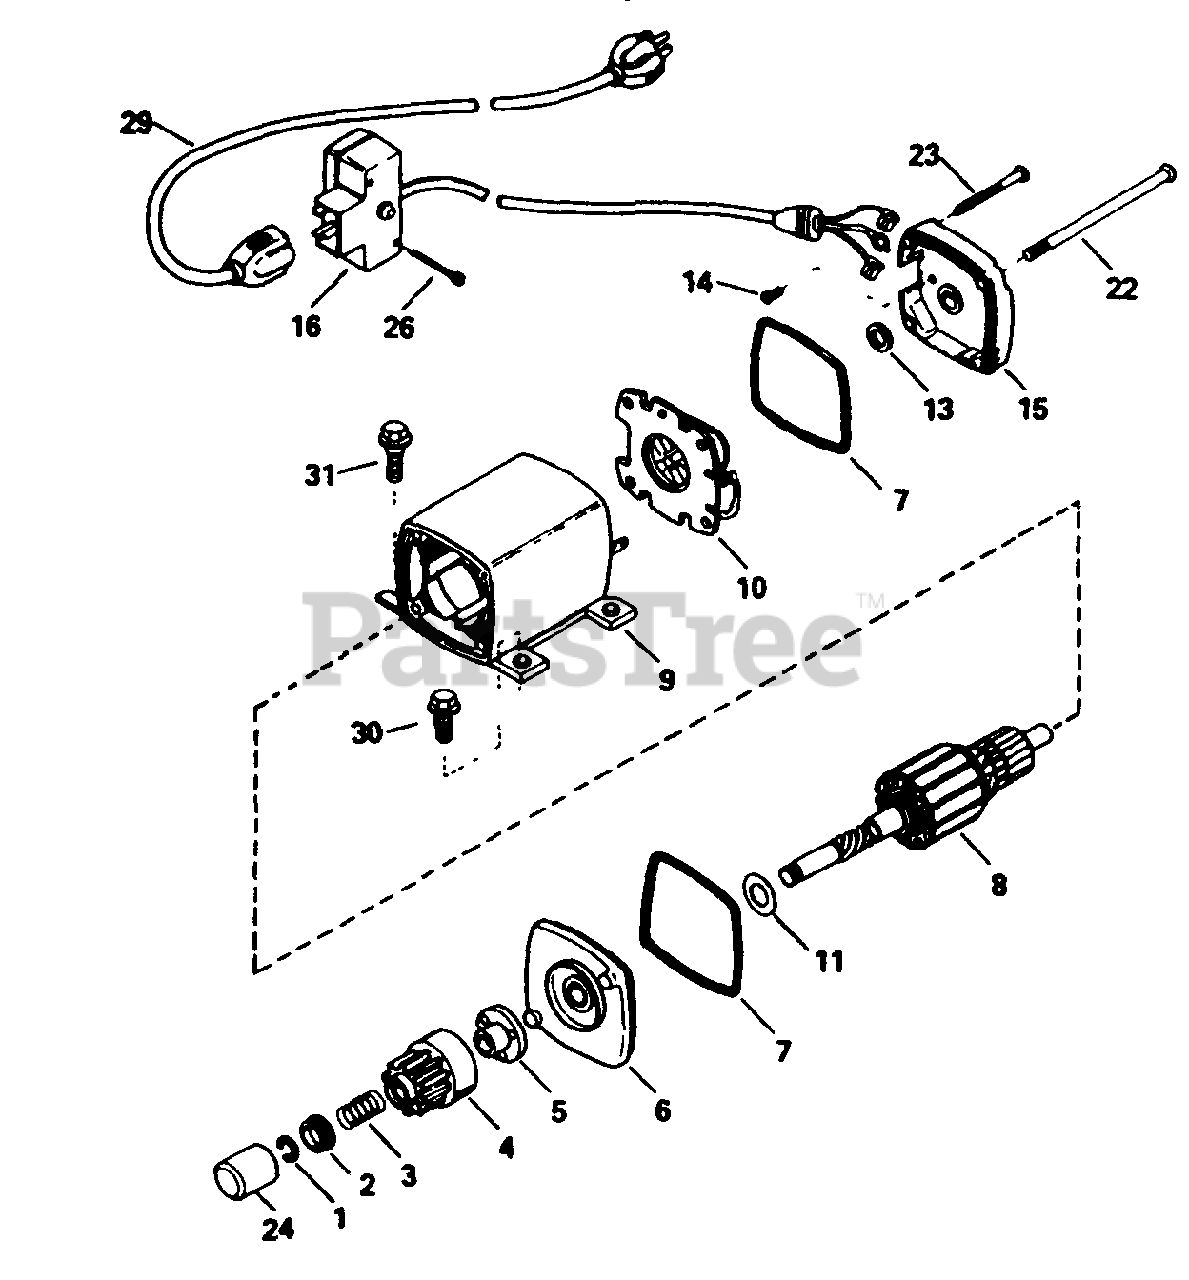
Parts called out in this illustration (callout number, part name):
1	Ring, Retainer
2	Retainer, Spring
3	Spring, Anti-drift
5	Nut and Retainer
6	Cap Ass'y., Drive End
9	Housing Ass'y.
10	Card Ass'y., Brush
11	Washer, Thrust
13	Washer, Thrust
14	Screw, Ground
15	Cap Ass'y., Commutator End
16	Box Ass'y., Switch
22	Bolt, Case
23	Screw, Grounding
24	Cover, Dust
26	Screw, Hex Hd. Self-Tap, 6-32 x 2-1/2
29	Cord, Extension (10'6")
30	Screw, Fil. Hd. Sems, 1/4-20 x 9/16
31	Screw, Hex Hd. Shoulder, 1/4-20 x 1/2
